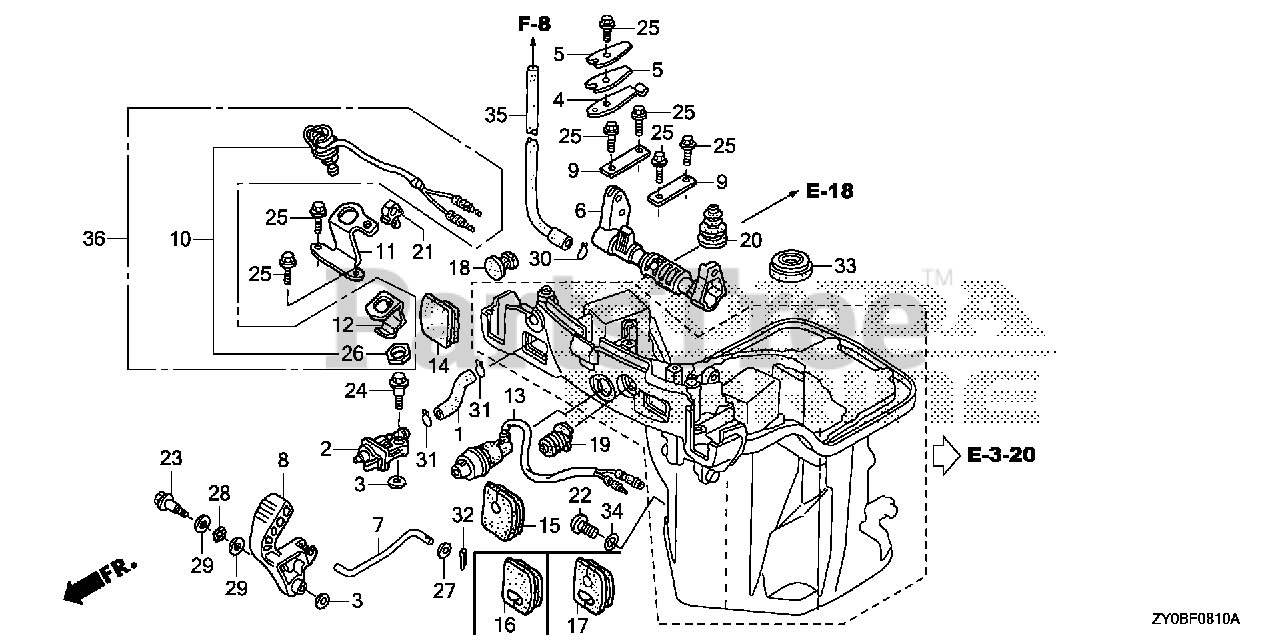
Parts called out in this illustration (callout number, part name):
1	TUBE A, FUEL
1	TUBE A, FUEL (FKM)
2	CONNECTOR ASSY., FUEL (B)
3	WASHER, PIVOT
4	SPRING, CLICK
5	SPRING, CLICK ASSIST
6	SHAFT, SHIFT
8	LEVER, SHIFT
9	PLATE, SHIFT SHAFT
10	SWITCH ASSY., NEUTRAL
11	BRACKET, NEUTRAL SWITCH
12	PLATE, NEUTRAL SWITCH
13	LAMP ASSY., INDICATOR
14	GROMMET A, OIL CASE
16	GROMMET B, OIL CASE
18	GROMMET F, OIL CASE
19	GROMMET D, OIL CASE
20	GROMMET E, OIL CASE
21	CLIP, BRAKE PIPE (A)
22	BOLT, OIL CHECK
23	BOLT, REVERSE LOCK
24	BOLT, SPECIAL (6X22) (CT200)
25	BOLT, FLANGE (5X12) (CT200)
26	NUT, HEX. (20MM)
27	WASHER, PLAIN (5MM)
28	WASHER, WAVE (10MM)
29	WASHER, PLAIN (9MM)
30	CLIP, TUBE (B10)
31	CLIP, TUBE
31	CLIP, TUBE (B12)
32	PIN, SPLIT (2.0)
33	SEAL, WATER (15X28X6)
34	O-RING (5.5X1.5)
35	TUBE, WATER CHECK
